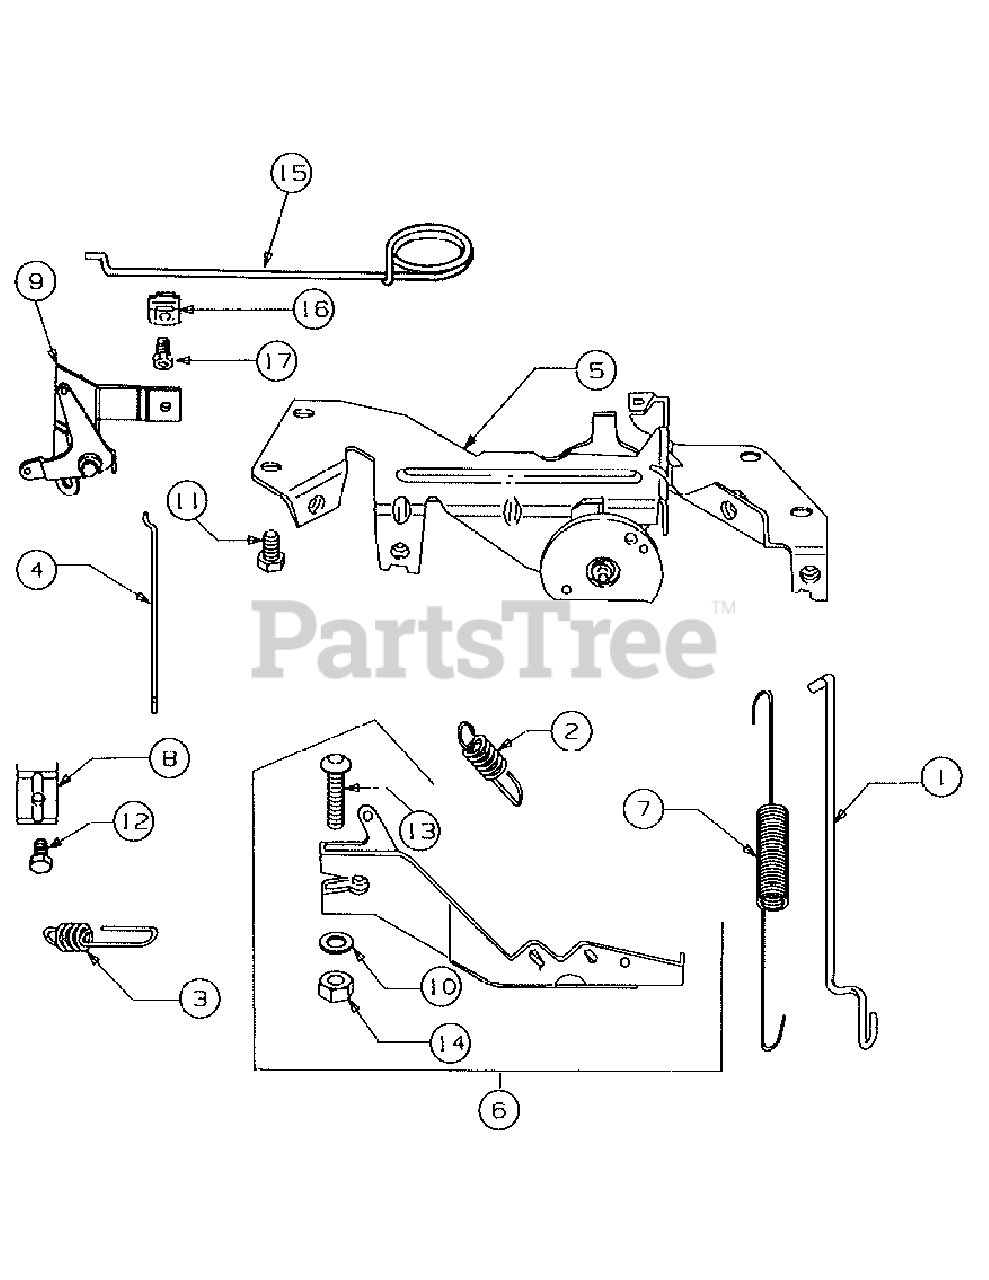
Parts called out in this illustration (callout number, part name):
1	Link, Governor
2	Spring, Governor
3	Spring, Governor Idle
4	Link, Choke
5	Bracket, Governor Control
6	Lever Assembly, Governor
7	Spring, Governor Link
8	Clamp, Casing
9	Bracket, Choke Control
11	Screw, Sem
12	Screw, Hex Head
14	Nut, Hex
15	Rod, Manual Choke
16	Clip, Friction
17	Screw, Sem
